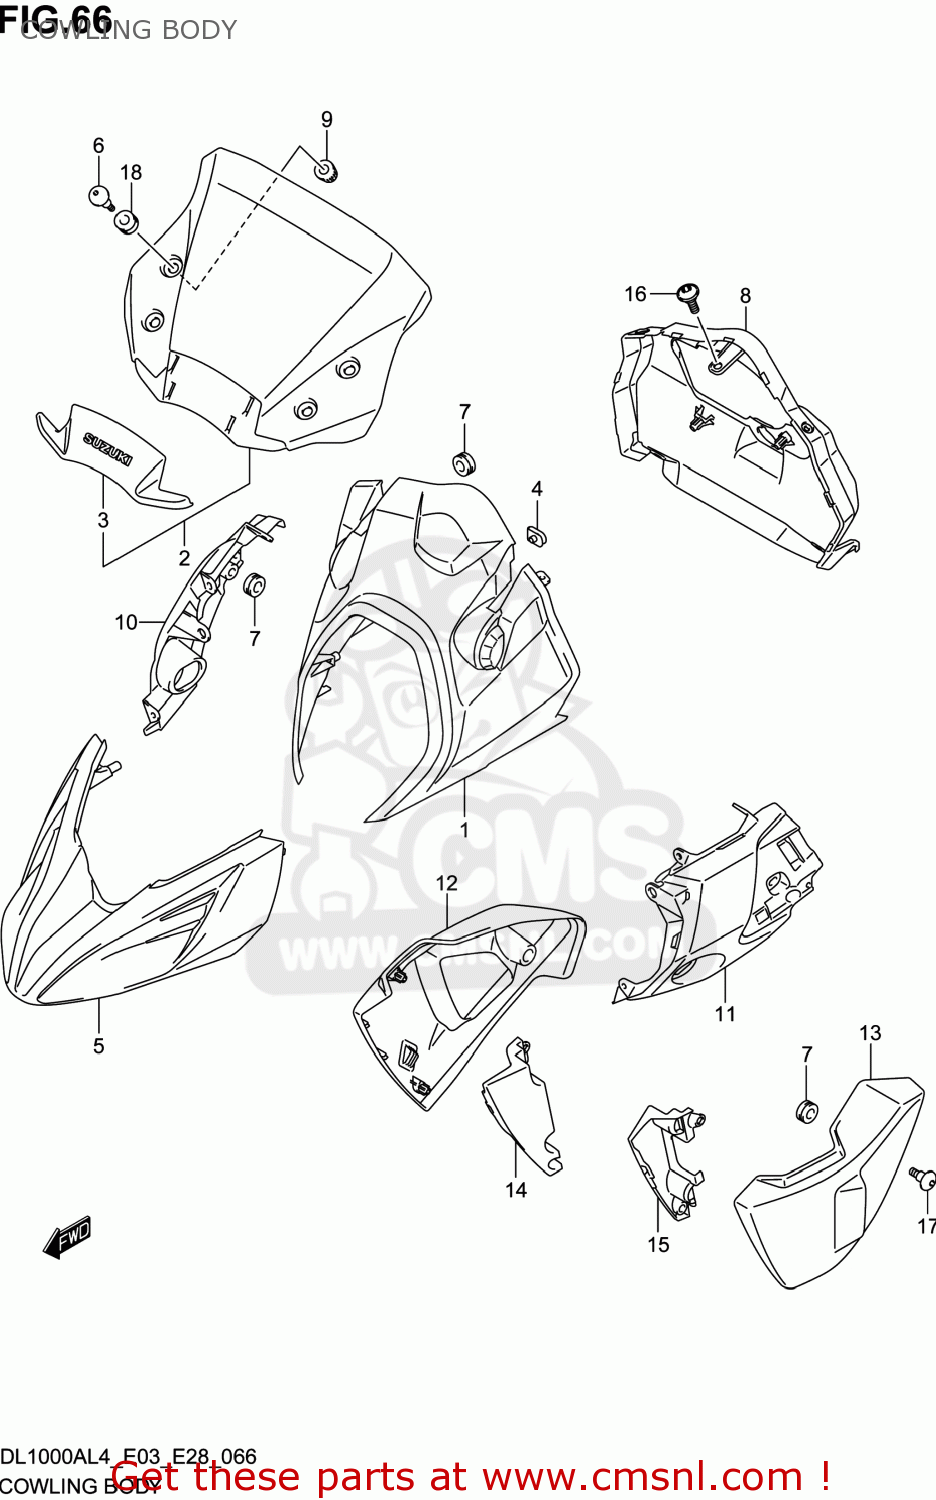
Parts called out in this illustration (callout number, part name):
1	COWLING,BODY
2	WINDSCREEN(BLACK)
3	COVER,WINDSCREEN
4	NUT
5	COWLING,BODY LOWER
6	SCREW(6X20)
7	CUSHION
8	PANEL,METER
9	CAP,WINDSCREEN SCREW
10	COVER,SIDE FR,R
11	COVER,SIDE FR,L
12	COWLING,SIDE LOWER,R
13	COWLING,SIDE LOWER,L
14	COVER,SIDE COWL INNER,R
15	COVER,SIDE COWL INNER,L
16	BOLT(5X13)
17	SCREW
18	CUSHION
